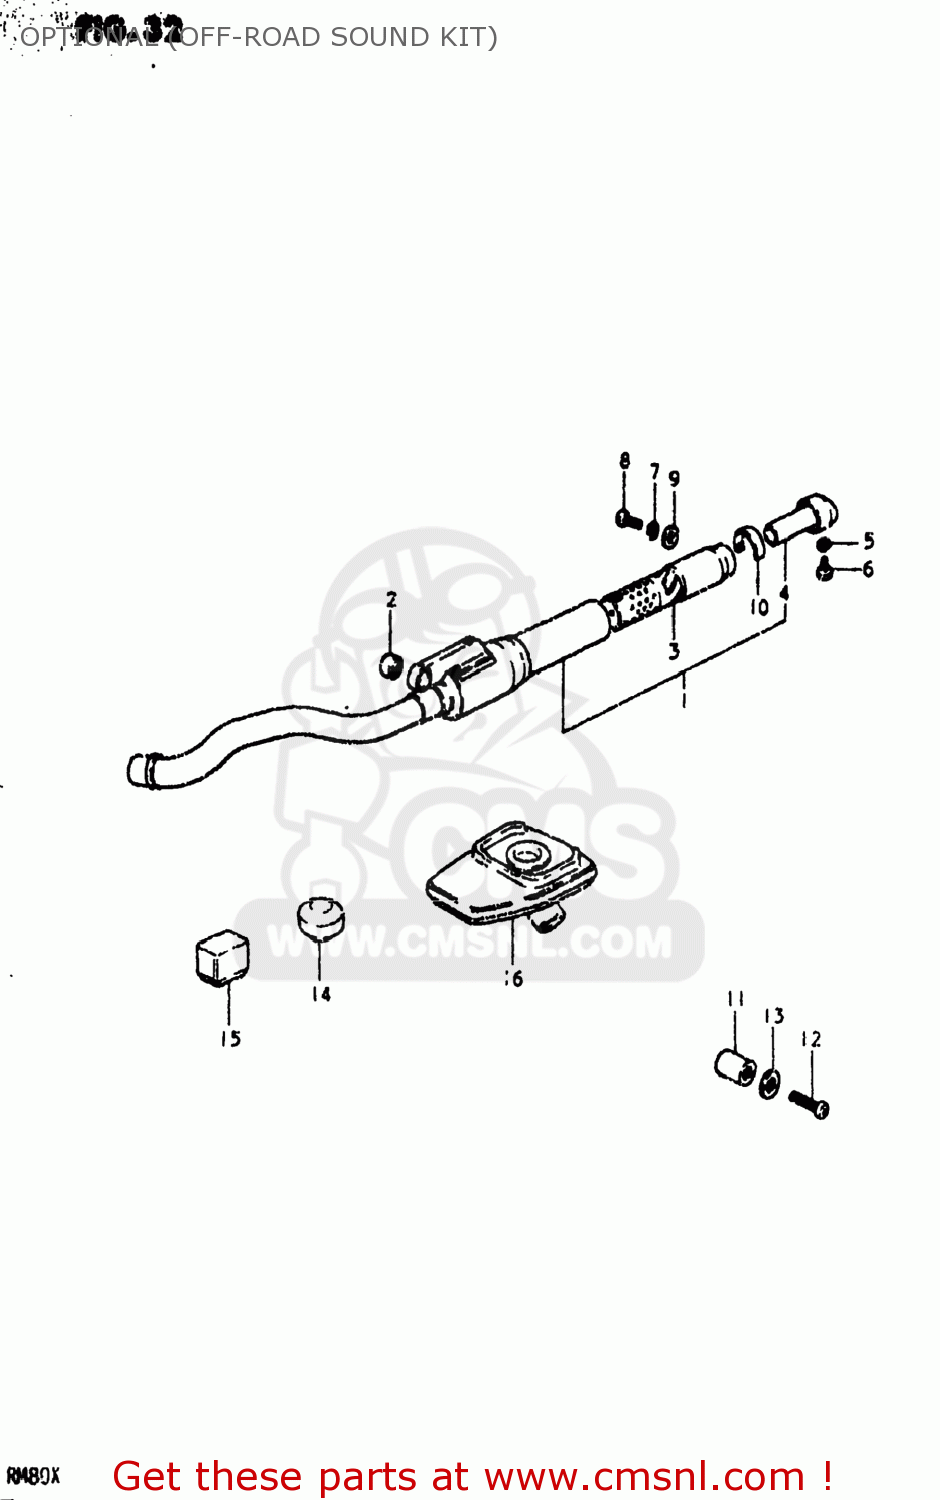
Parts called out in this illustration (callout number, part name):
1	MUFFLER ASSEMBLY
2	BUSHING
3	ARRESTER,SPARK
4	TUBE,MUFFLER CLEAN OUT
5	LOCK WASHER
6	SCREW
7	LOCK WASHER
8	SCREW(6X8)
9	WASHER
10	BAND,SPARK ARRESTER
11	SPACER (6.8X10X10)
12	SCREW
13	WASHER
14	PAD,CYLINDER
15	PAD,CYLINDER
